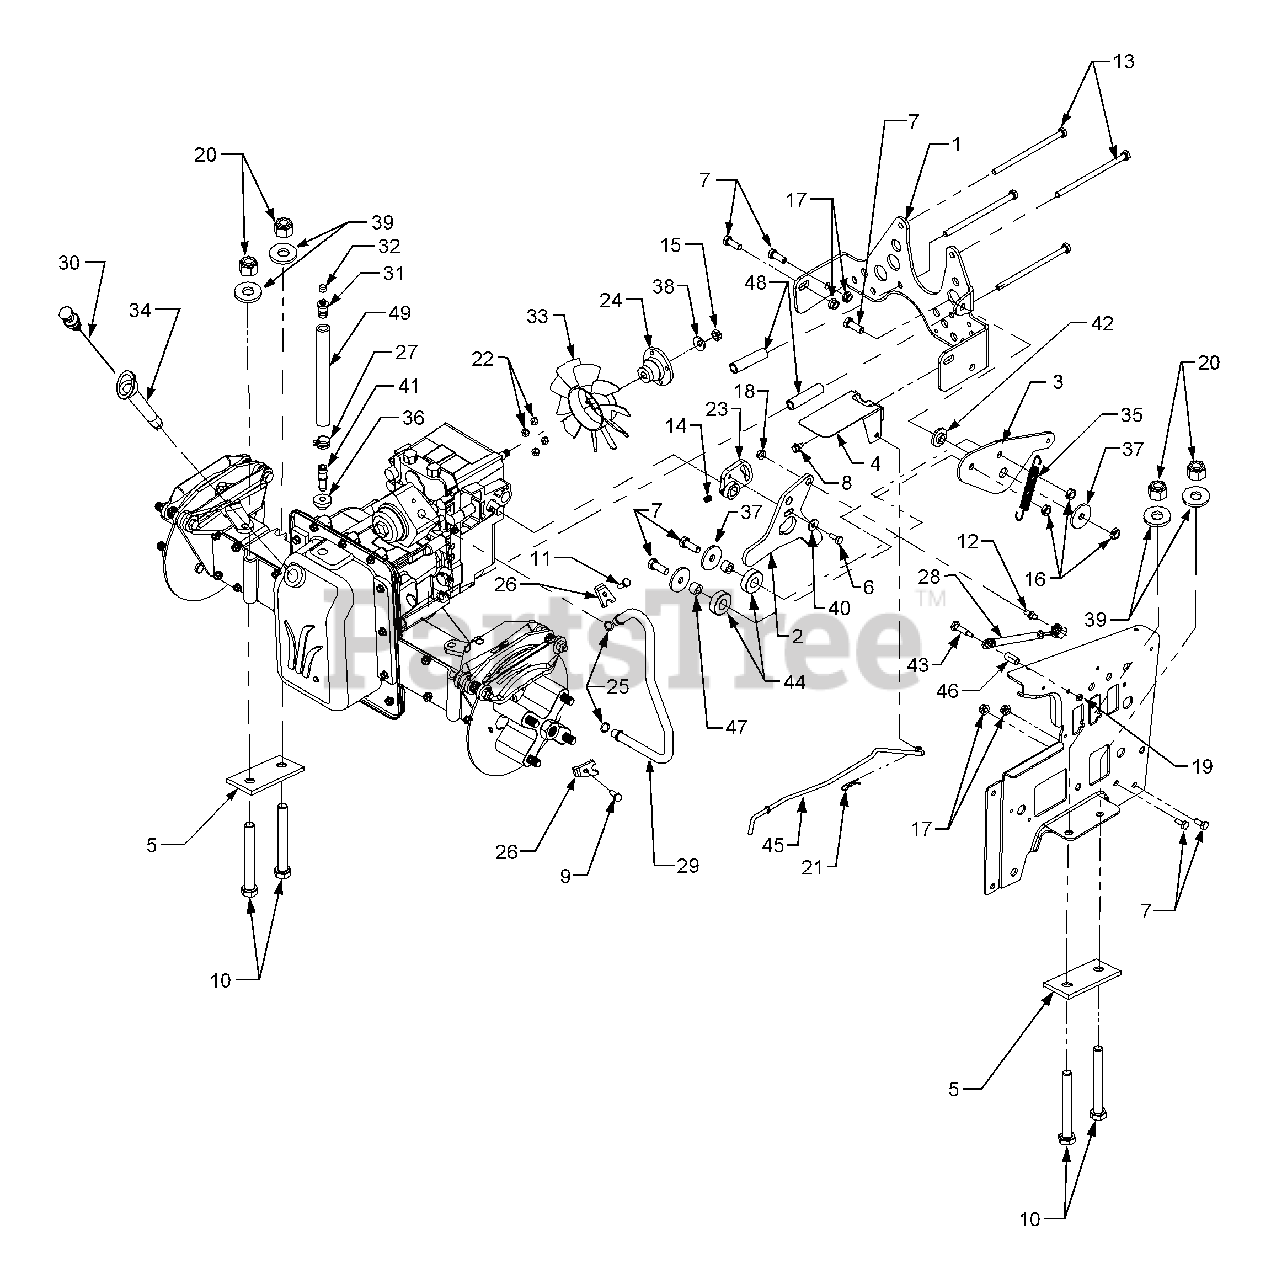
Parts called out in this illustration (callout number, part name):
1	Bracket, Torque
2	Plate, Hydro Neutral Return
3	Link, Neutral Return Bearing
4	Spring Plate, Hydro Bypass
7	Screw, Hex Cap, 3/8-16 x 1.0 GR5
8	Screw, Hex Wash. Hd. Tapp, 1/4-20 x .5
9	Screw, Hex Wash. Hd. Tapp, 1/4-20 x .75
10	Screw, Hex Cap, 1/2-20 x 4.5 GR5
11	Screw, Hex Cap, 1/4-20 x .75 GR5
12	Ball Screw, 5/16-18 x .56
13	Screw, Hex Wash. Hd. Tapp, 5/16-18 x 5.5 GR5
14	Screw, Set, 5/16 x .5
15	Nut, Hex Ctr. Lock Jam, 3/8-24
16	Nut, Hex Ctr. Lock Jam, 3/8-16
17	Nut, Hex Flange Lock, 3/8-16
18	Nut, Hex Flange Lock, 5/16-18
19	Nut, Hex, 1/4-20
20	Nut, Hex Insert Lock, 1/2-20
21	Pin, Internal Cotter
22	Nut, Fan, 1/4-20
23	Arm, Hydro
24	Adapter, Pump
25	O-Ring, .426 ID x .566 OD x .070
26	Clamp, Tube
27	Clamp, Hose
28	Cylinder, Damper
29	Tube, Hydro Pickup
30	Dipstick, Transmission
31	Plastic Vent
33	Fan, Pump
34	Holder, Dipstick
35	Spring, Extension
37	Washer, Flat, .390 x 1.5 x .1
38	Washer, Bell. .401 x .87 x .063
39	Washer, Flat, .531 x 1.062 x .134
40	Washer, Flat, .26 x .72 x .06
41	Fitting, Tube
42	Spacer, Shoulder
43	Shoulder Bolt
44	Bearing, Ball
45	Rod, Pump Bypass
46	Spacer, .375 x .5 x 1.02
47	Spacer, .375 x .624 x .445
48	Spacer, Hydro, .3223 x .60 x 2.44
